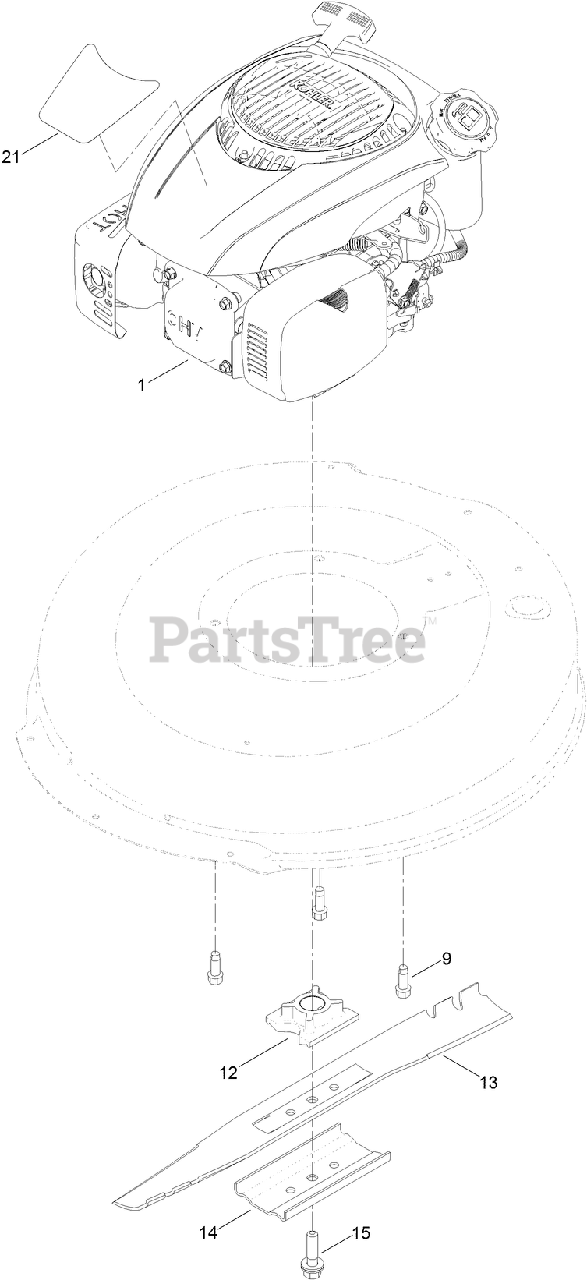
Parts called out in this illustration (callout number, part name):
9	SCREW-TAPTITE
12	RETAINER-BLADE
14	SUPPORT-BLADE
15	BOLT-BLADE
